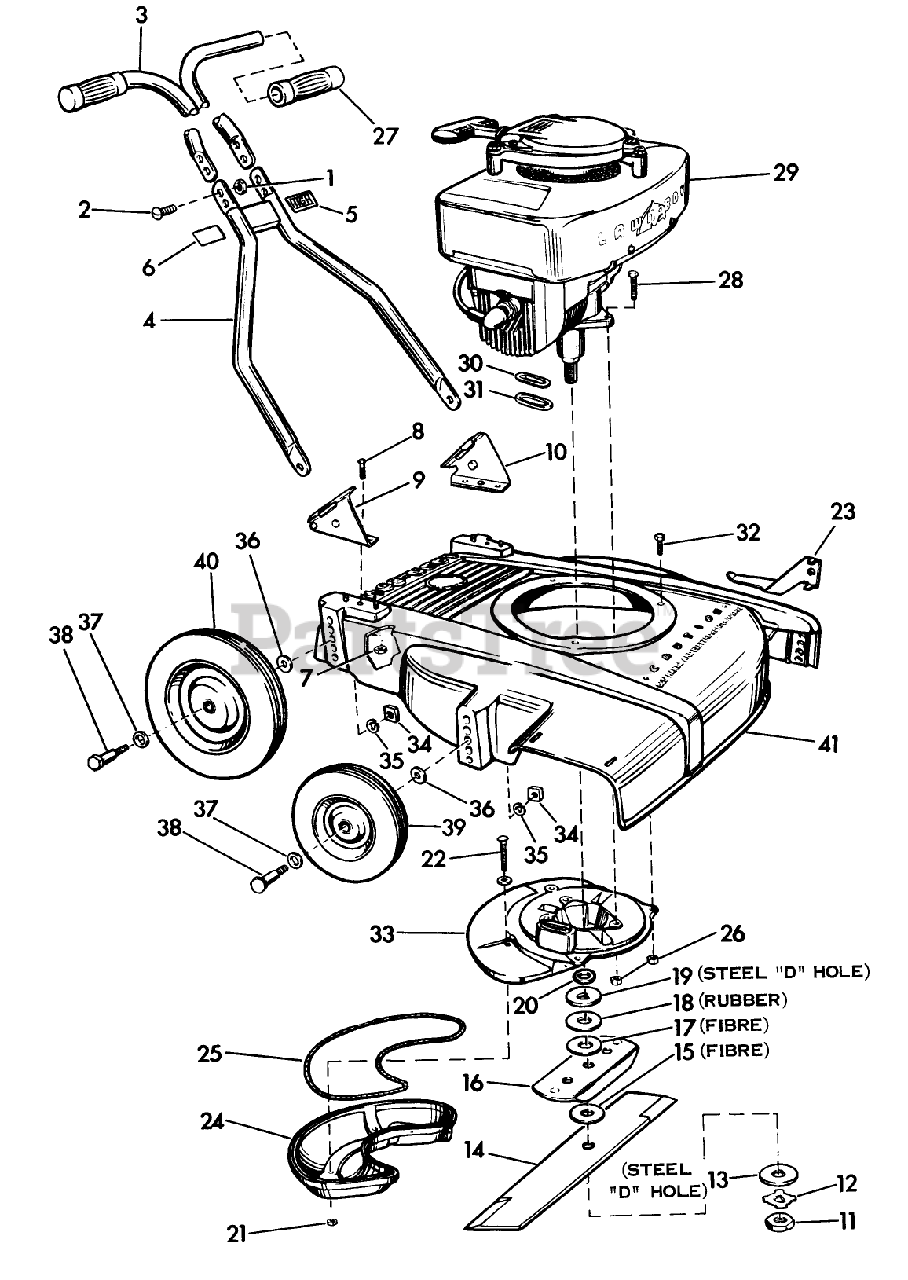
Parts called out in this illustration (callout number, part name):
1	STOP NUT
5	Decal-Handle "High"
6	Decal-Handle "Low"
11	Nut-Blade
13	Washer-Steel "D" Hole
14	Blade-21"
18	BLADE WASHER
19	Washer-Steel "D" Hole
21	LOCKNUT E
23	Skid-Wheel
27	Grip-Handle
29	Engine
35	WASHER, LOCK
41	Housing-18"
41	Housing-21"
